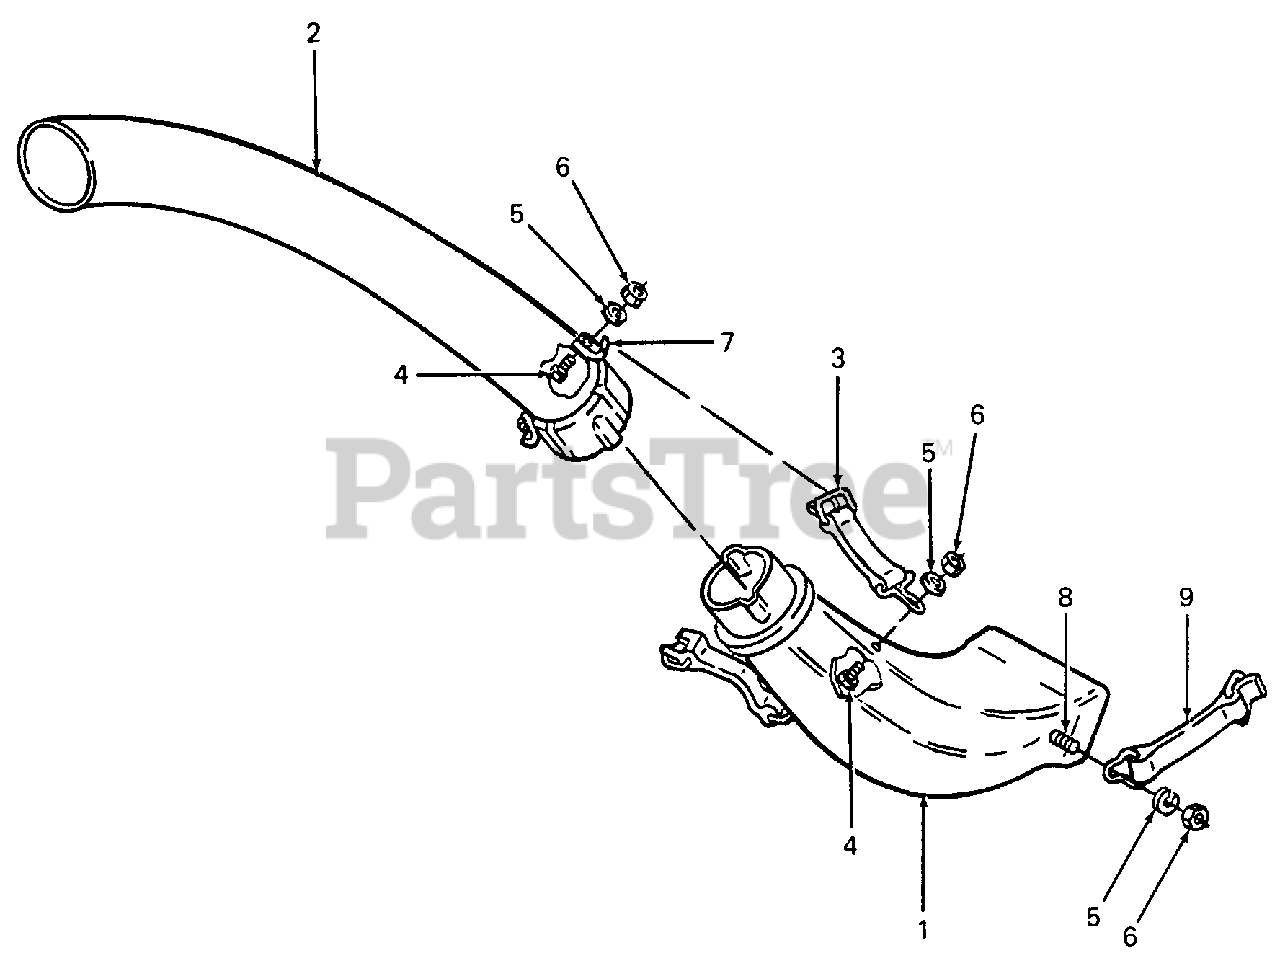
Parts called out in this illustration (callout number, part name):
1	Chute, Discharge
2	Elbow, Catcher
3	Strap Assy, Retainer
4	Screw, Hex, 1/4-20 X .50 Lg
5	Washer, Spring, .265 X .562
6	Nut, Hex Insert Lock, 1/4-20
7	Hook Bracket, Retainer
8	Screw, Hex Cap, 1/4-20 X .62 Lg
9	Strap Assy, Retainer
